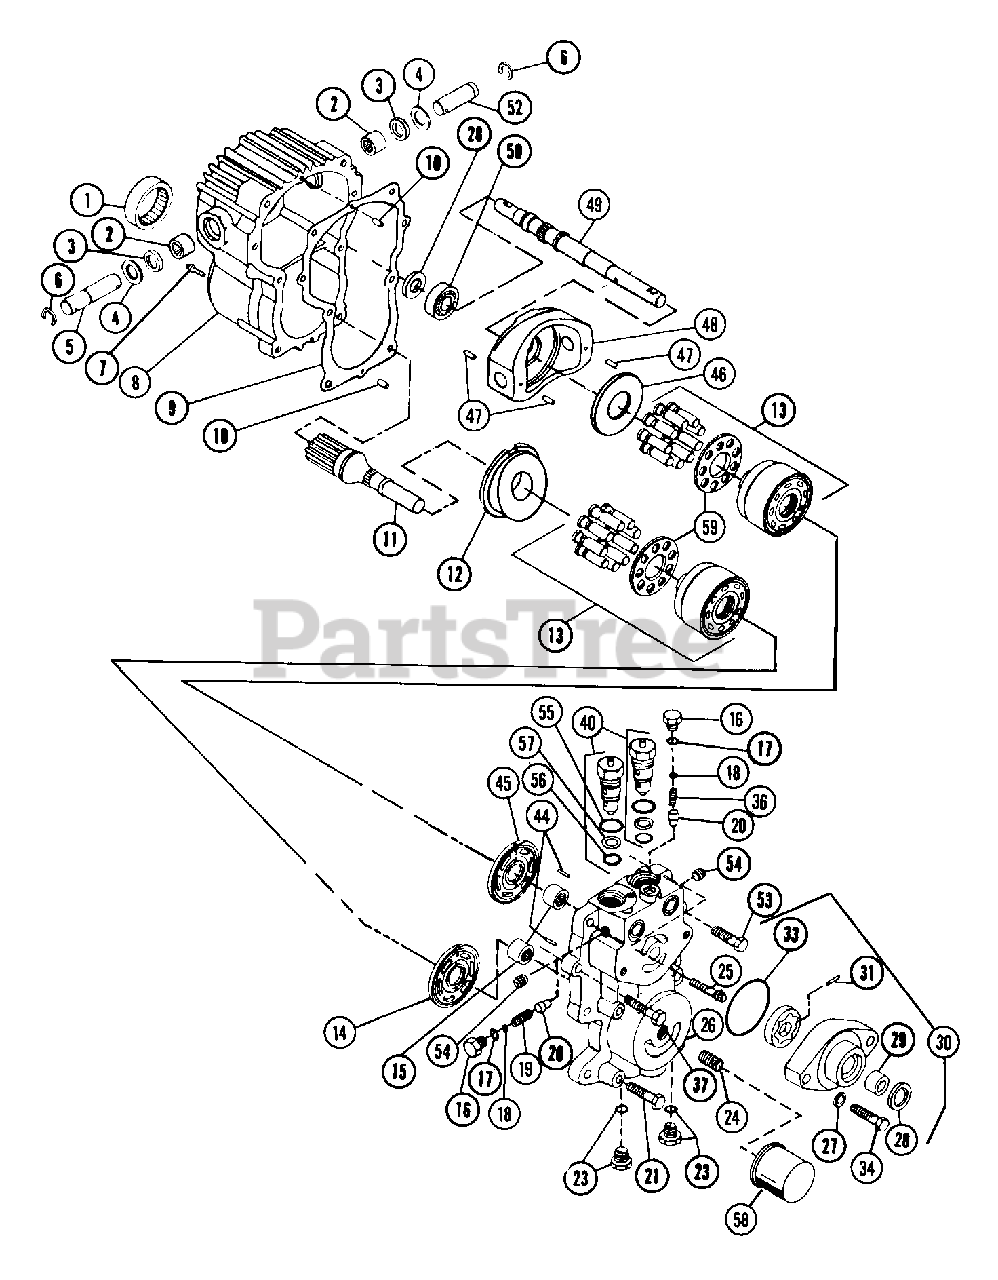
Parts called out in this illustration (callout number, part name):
1	BRG-ROLLER 1.27X2.05X15MM
2	BRG-NEEDLE .688X.876X.63
3	SEAL .625X1.187X.187
4	WSHR-FL-STL .469X1.380X.125
5	TRUNNION SHAFT
6	RG-RTNG-EXT .688X.042
7	SCR-12PNT .25-20X.88 GR5
8	HOUSING
10	DOWEL PIN
11	MOTOR SHAFT
12	SWASH PLATE
13	CYLINDER BLOCK KIT
14	MOTOR VALVE PLATE
15	BRG-NEEDLE 17MMX.938X.62
16	PLUG-HEX HEAD
17	O-RING .414X.562X.072
18	SHIM PACKAGE
19	SG-COMP ??X??X?? SUNSTRAND
20	RELIEF VALVE CONE
21	BLT-HEX .38-16X2.00 PL GR5
23	THREADED PLUG
25	BLT-HEX .44-14X2.00 GR5
26	CENTER SECTION
27	WSHR-FL-STL .469X.719X.108
28	SEAL .625X1.128X.250
29	BRG-NEEDLE .625X.875X.50
30	CHARGE PUMP KIT
31	DOWEL PIN
33	O-RING 2.364X2.504X.072
34	SCR-12PNT .38-16X1.25 GR5
36	SG-COMP SUNSTRAND
37	BLT-HEX .38-16X1.25 PL GR5
40	CHECK VALVE ASSEMBLY
44	DOWEL PIN
45	PUMP VALVE PLATE
46	THRUST PLATE
47	PIN-ROLL .188X.63
48	SWASH PLATE
49	STEERING COLUMN CLAMP
50	BRG-BALL 17MMX40MMX12MM
52	TRUNNION SHAFT
53	BLT-HEX .38-16X1.50 PL GR5
54	PIPE PLUG
55	O-RING .770X.968X.097
56	O-RING .614X.750X.070
57	O-RING .614X.750X.046
58	OIL FILTER
59	SLIPPER RETAINER
